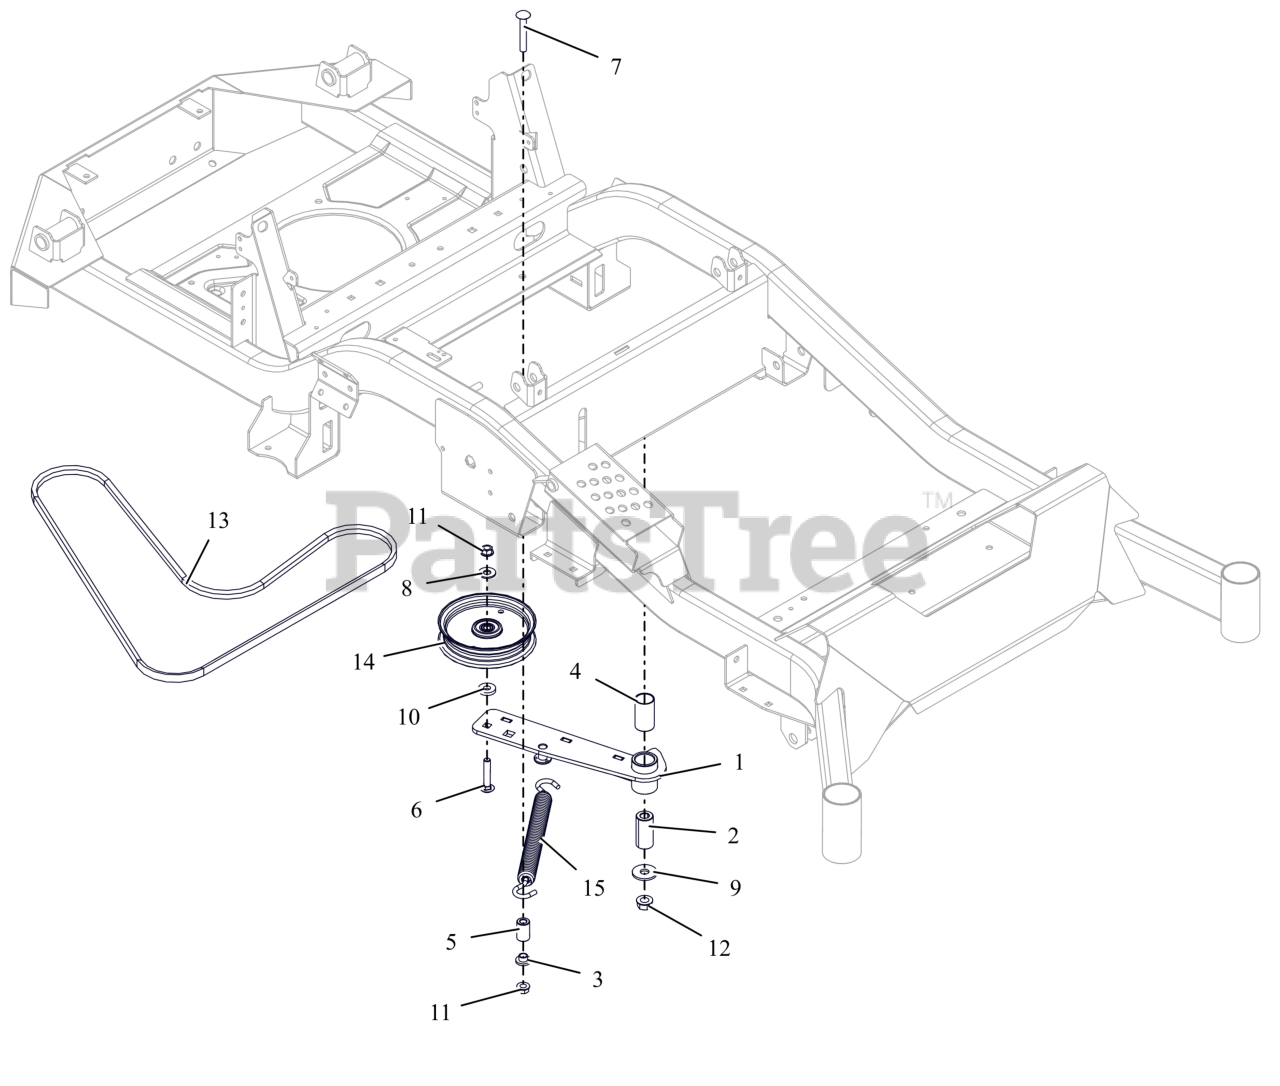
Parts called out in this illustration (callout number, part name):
1	WLDMT, HYDRO DRIVE IDLER ARM (BLACK)
2	BSHG, SPCR .502X.997X2.03 PM
3	BSHG-FLG .385X.500X.875X.406
4	BSHG, 1.00X1.125X1.937
5	BUSHING, SLV .380X.750X1.190
6	BLT, RHSN .38-16X2.00 G5 ZCC
7	BLT, RHSSN.38-16X2.50 G5 ZCC
8	WSHR,FLT .438X1.00X.083 ZCC
9	WSHR-FL-STL.511X1.44X.125ZC120
10	WSHR, FLT .406X1.00X.188 ZCC
11	NUT-LK-TOP-FLG .38-16 ZC120
12	NUT-LK-TOP-FLG .500-13 GF ZCC
13	V-BELT, 4L-WRAPPED
14	IDLER- FLAT - 5.00" X .75"
15	SPRING, EXTENSION
